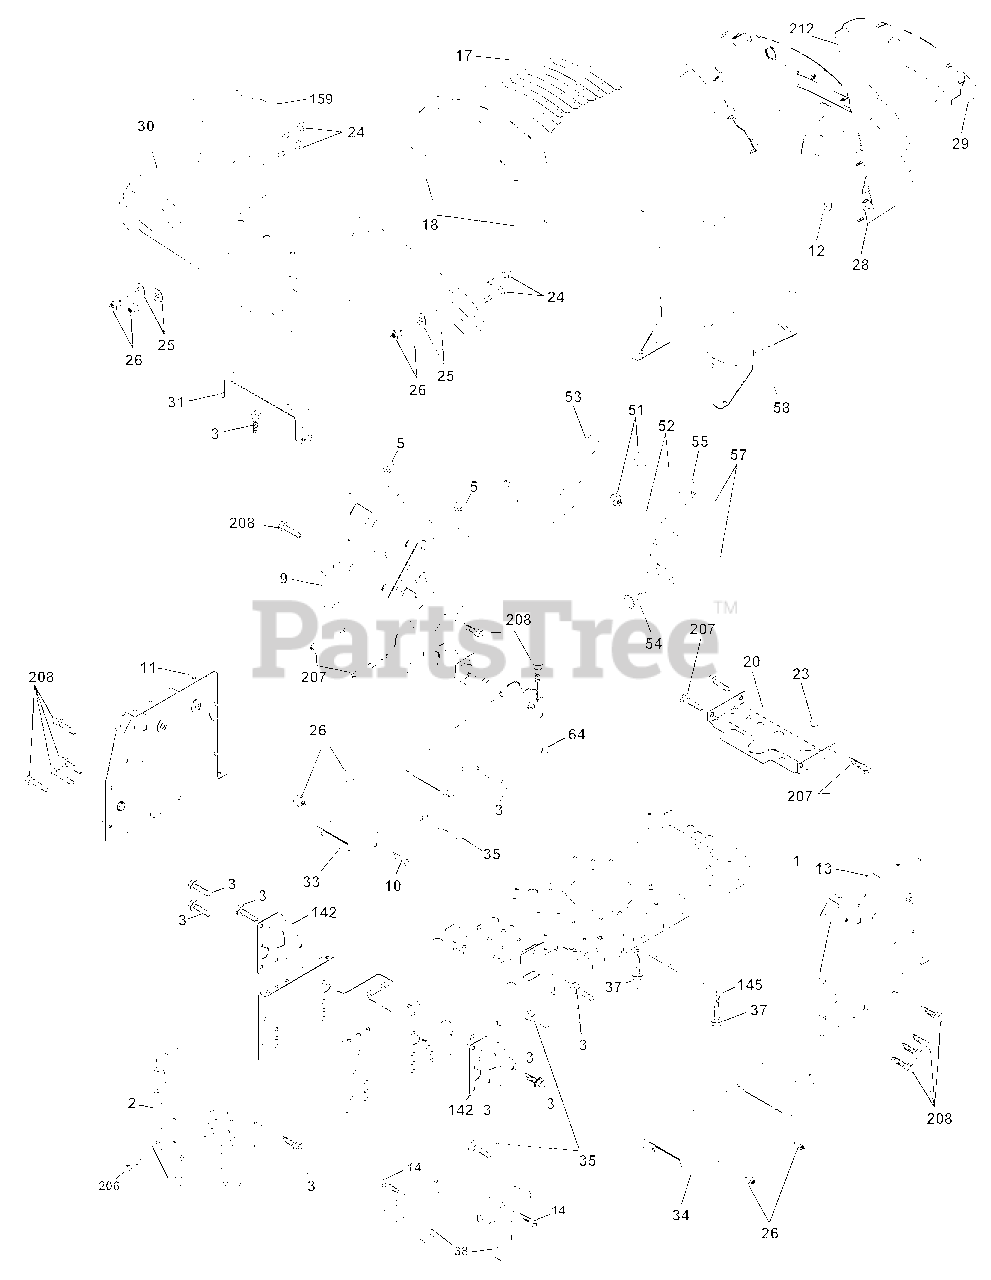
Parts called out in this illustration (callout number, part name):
1	Chassis
2	Drawbar
3	Screw 3/8-16 X .75
5	Bumper Hood/Dash
9	Dash P/L
10	Bolt Carriage 3/8-16 x 1
11	Panel Dash Lh
12	Clip Tinnerman
13	Panel Dash Rh
14	Screw Thdrol 3/8-16 x 1/2
17	Hood LT/PL
18	Bumper Hood
20	Plate Mtg Battery Fuel Tank Fr
23	Bushing
24	Bolt Fin Hex 3/8-16 x 1 Gr 5
25	Washer 13/32 X 13/16 X 12 Ga
26	Nut Lock Hex W/Ins 3/8-16 Unc
28	Grille/Lens Asm
29	Lens LT/PL
30	Fender Footrest STLT Pnt
31	Bracket Fender
33	Footrest Pnt Lh
34	Footrest Pnt Rh
35	Bolt Rdhd Sht Sqnk 3/8-16 x 3/4
37	Screw Thdrol 6/16-18 x 1/2 TYT
38	Bracket Asm Pivot Mower Rear
51	Nut Lock Hex W/Ins 1/4-20
52	Washer 9/32 x 7/8 x 16 Ga.
53	Bracjet Grukke Lh
54	Screw Hex Wshd 8-18 x 7/8
55	Bracket Grille Rh
57	Bolt Hex 1/4-20 x 3/4
58	Duct Air
64	Dash Lower STLT
142	Plate Reinforcement STLT
145	Rod Pivot Chassis/Hood
159	Cupholder
206	Bolt Shoulder 5/16-18
207	Screw Thdrol 5/16-18 x 1/2
208	Screw Thdrol 3/8-16 x 1/2
212	Insert Lens Relect
